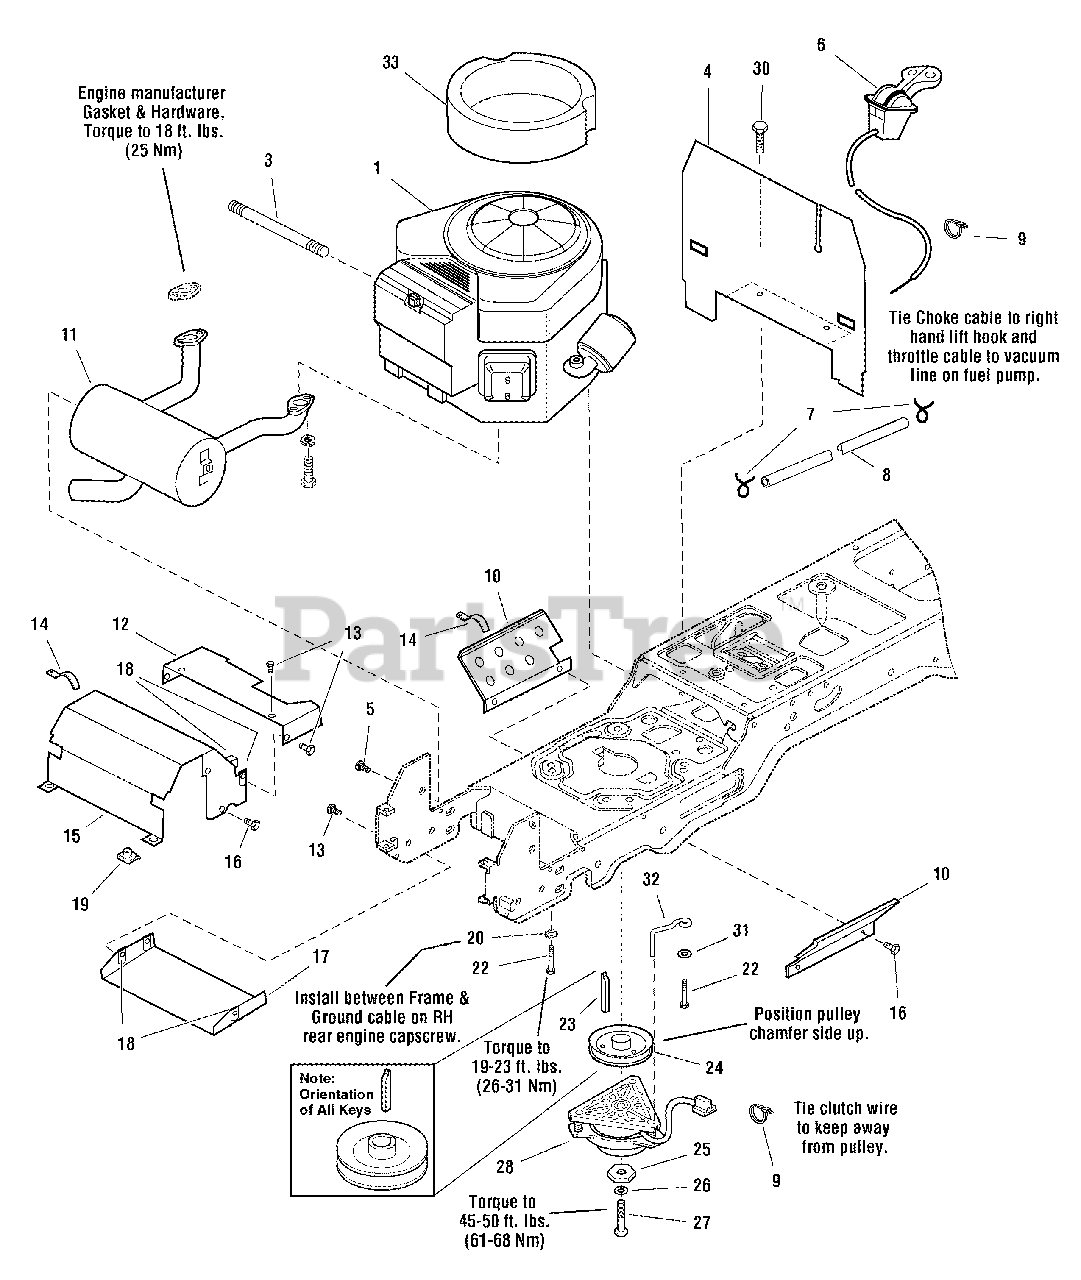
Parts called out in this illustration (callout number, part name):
1	* ENGINE, 25HP Kohler Command Twin - Model CV730S, PS-CV730-3113
3	HOSE, Oil Drain
4	BULKHEAD
5	SCREW, Hex Washer Head Taptite 5/16-18 x 1/2
6	THROTTLE, Control Double 51.0 LG w/Knobs
7	CLAMP, Hose
8	HOSE, Fuel
9	TIE, Self Locking
10	SHIELD, Side
11	MUFFLER, Kohler Twin
12	DUCT, Muffler
13	SCREW, Hex Whiz Lock Flange 1/4-20 x 5/8
14	CLIP, Speed Wire
15	DUCT, Muffler Top
16	SCREW, Hex Washer Head Taptite 1/4-20 x 3/8
17	SHIELD, Muffler
18	NUT, Speed 1/4-20 Lug Type
19	NUT, Speed, Lug Type, 5/16-18
20	LOCKWASHER, External Tooth 3/8
22	SCREW, Hex Washer Head Taptite 3/8-16 x 1-1/2
23	KEY, Hi-Pro, 2.5" x .250" Square
24	PULLEY & HUB ASMY
25	WASHER, Hex
26	LOCKWASHER, Spring
27	CAPSCREW, Hex Head 7/16-20 x 3-1/2 G5
28	CLUTCH, Electric, Ogura, Adjustable
30	SCREW, Hex Washer Head Taptite 1/4-20 x 1/2
31	WASHER, 3/8
32	RETAINER, Clutch
33	EDGING, Rubber
